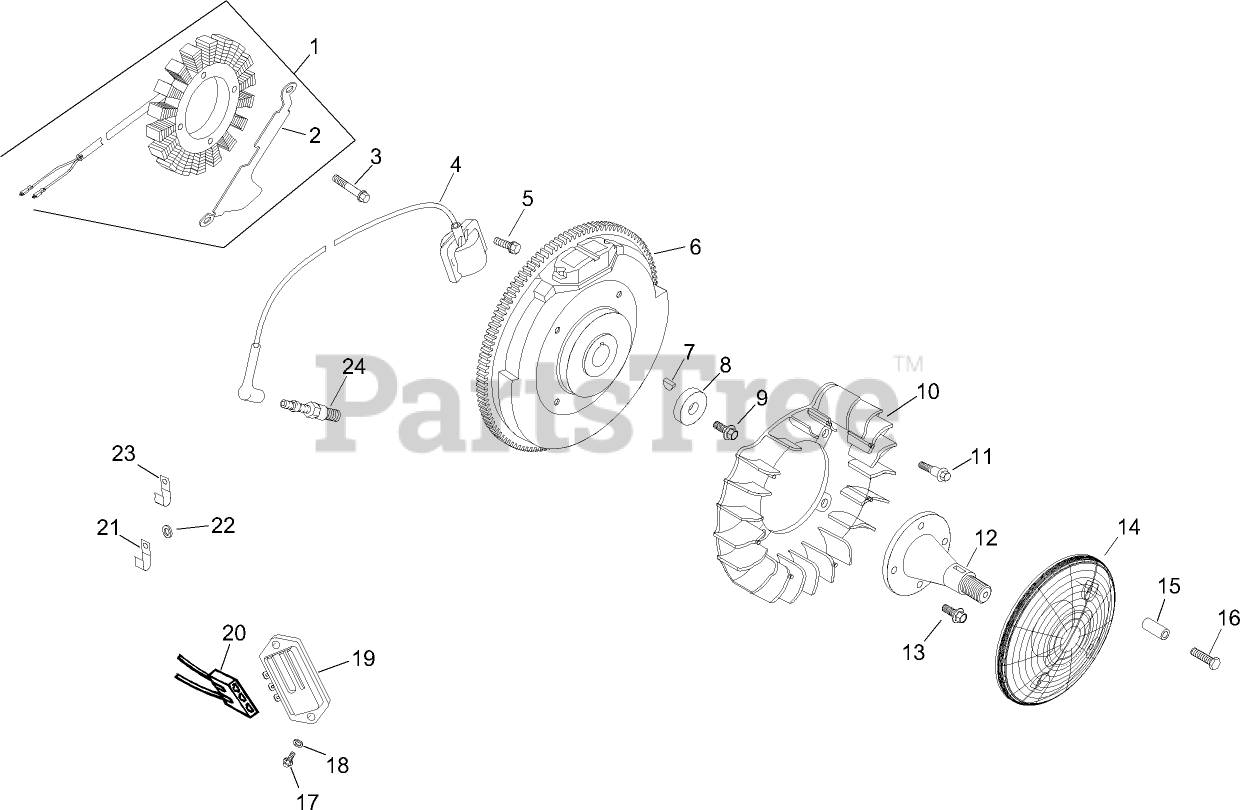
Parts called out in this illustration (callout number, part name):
1	15 Amp Stator Kit (Includes 2)
2	Bracket-Wire, Stator
3	SCREW-THREAD FORMING (M5X0.8X25)
4	Module-Ignition
5	SCREW-FLANGE, THREAD FORMING (M5X.8X20)
6	Flywheel
7	KEY (3/16 X 5/8)
8	WASHER-FLAT (13/32)
9	SCREW-FLANGE (M10X1.5X45)
10	Fan
11	BOLT-SHOULDER (M6x1.0x16)
12	Shaft-Drive, Front
13	Screw-HF (M8x1.25x25)
14	Screen-Grass
15	Spacer
16	SCREW-FLANGE, SEMS (M4X.7X25)
17	SCREW-PHL HD (11-16X.88)
18	WASHER-FLAT (.188)
19	Rectifier-Regulator
20	Connector (3 contact)
21	CLIP-CABLE
22	WASHER-FLAT (1/4)
23	Clip-Cable
24	SPARK PLUG (PRO SERIES)
